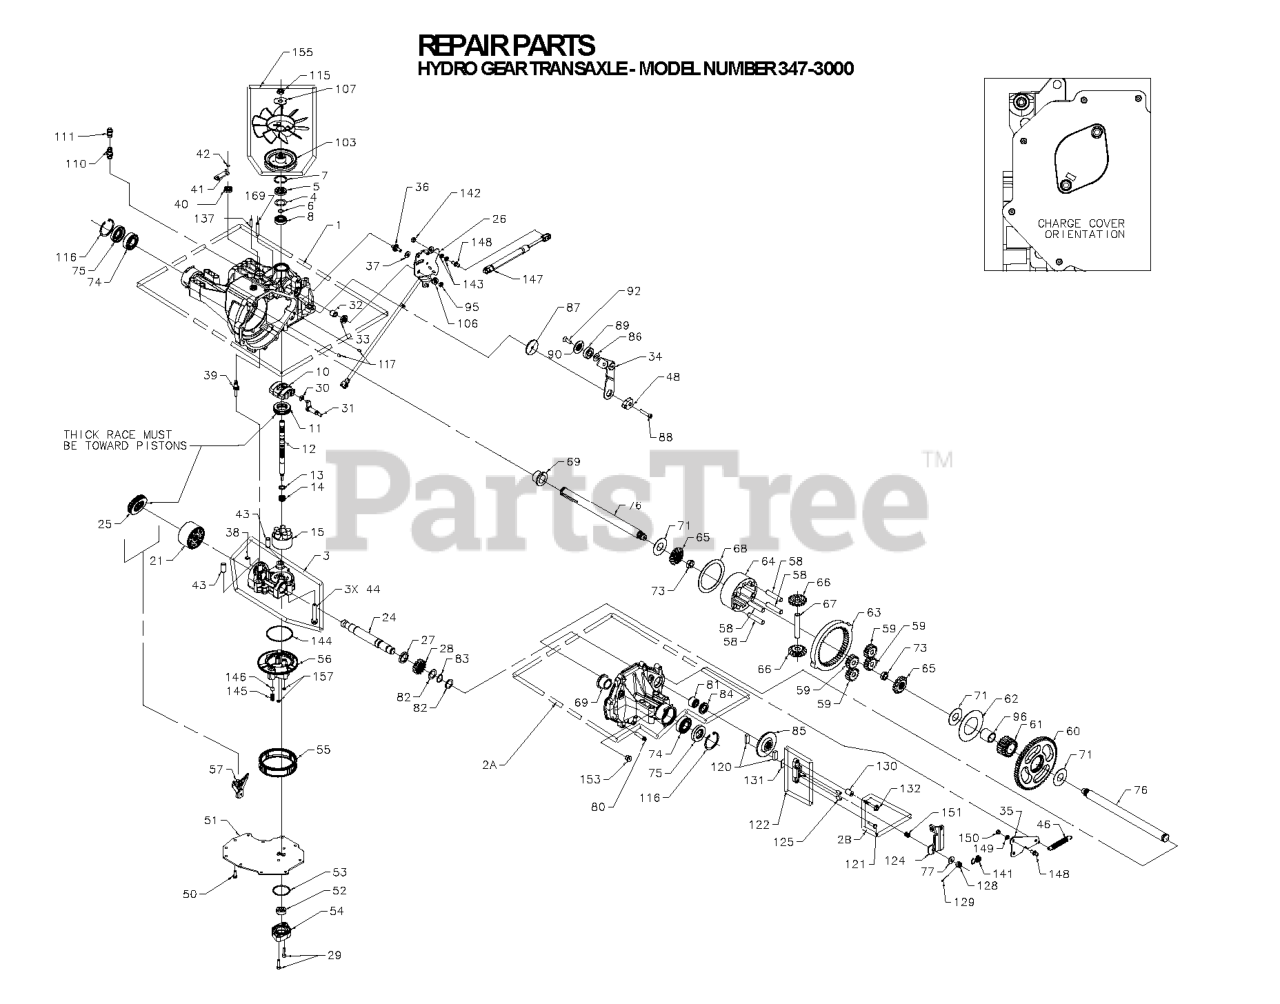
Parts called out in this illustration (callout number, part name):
5	SEAL.LIP.H-G.(9008000-0128)
6	RING RETAINING 2003016
7	RING.RETAINING.(2003052)
8	BALL BEARING
10	SWASHPLATE (2003087)
11	BEARING, THRUST 50551
14	SPRING 2003014
30	SLOT GUIDE
37	DAMPENER PUCK
39	BYPASS ACTUATOR
41	BYPASS ARM
42	RETAINING RING 44870
53	O-RING.HYDRO GEAR.9004101-1340
75	SHAFT, MOTOR
77	WASHER .34X.88X.06.44130
80	TORX.SCREW. 50868
95	NUT.LOCK.HX.(H-G PART 50108)
110	O-RING KIT 70110
111	CAP, VENT ASSY
120	BRAKE PUCK (44132)
121	BOLT W/NYLOCK 44433
125	BRAKE PIN 44127
128	CASTLE NUT
131	PUCK PLATE 44134
142	NUT 5/16-18 HEX LOCK 43064
